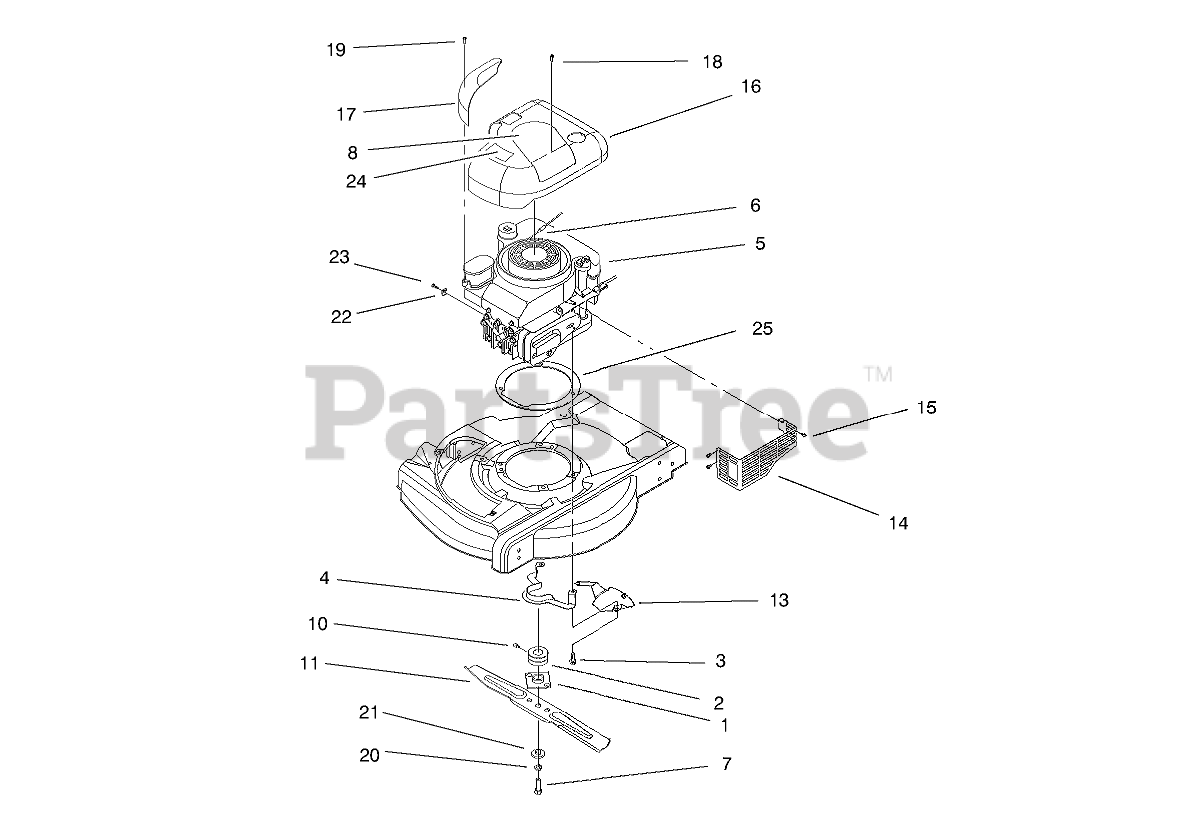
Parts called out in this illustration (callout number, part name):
1	PLATE AND COLLAR ASM
2	PULLEY
3	SCREW-TAPTITE
4	Guide-Belt
6	STOP-ROPE
7	SCREW-BLADE
8	DECAL - RECOIL,4 CYCLE
10	SCREW-SET
11	Blade
13	Shield-Grass
14	SHIELD-MUFFLER
15	SCREW-HWH
16	Shroud-Engine
17	AIR CLEANER COVER ASM
18	Screw-Mtg
19	SCREW - AIR CLEANER F/W
20	WASHER-LOCK
21	SPACER-BLADE
22	CLAMP-CASING
23	SCREW-CLAMP
24	Nameplate-Engine
25	PLATE - ENGINE
